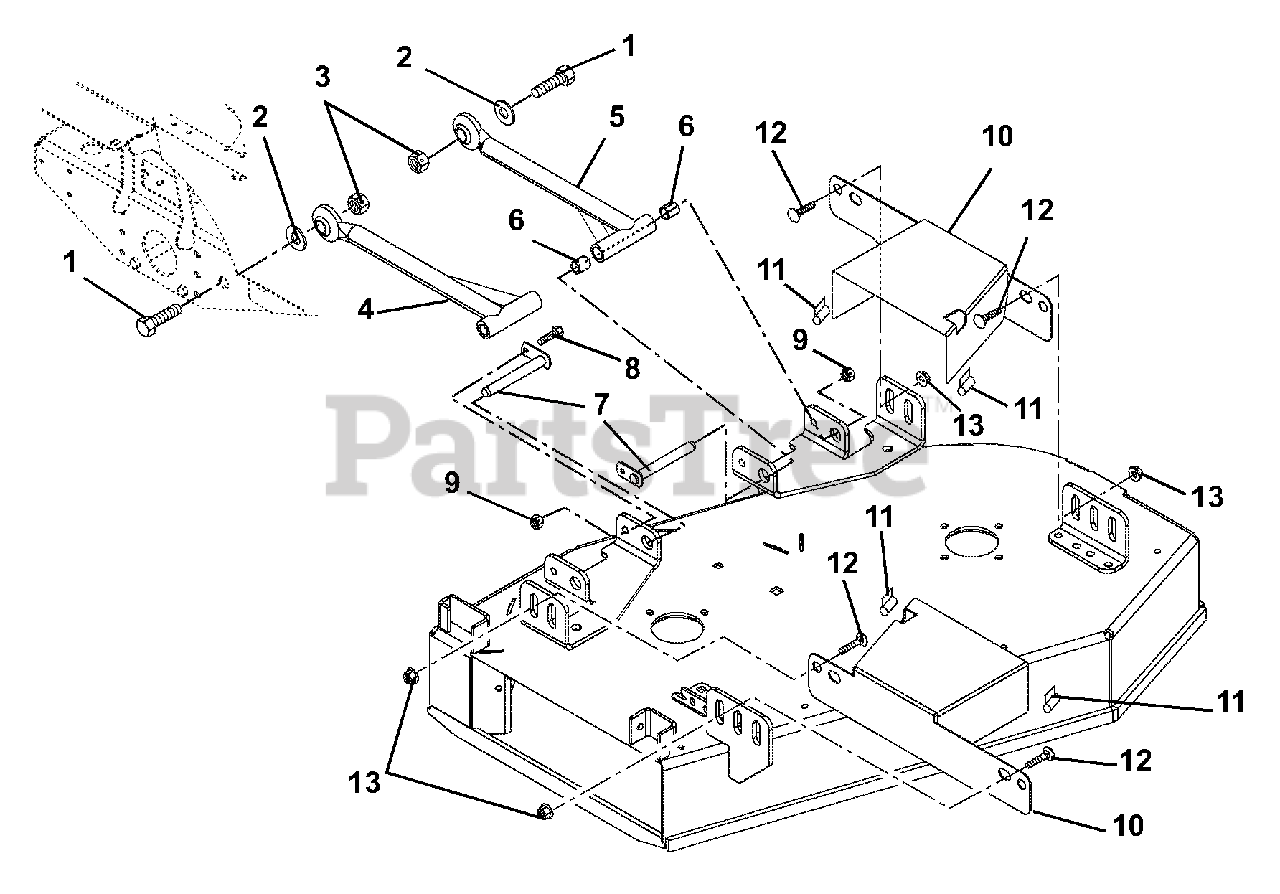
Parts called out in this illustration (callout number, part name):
1	BLT-HEX .875-9X3.00 GR5 YZ
2	BSHG-SLV .882X1.250X.531
3	NUT-LK-CTR .875-9 YWZC
4	ASSY, MOWER MOUNTING
5	MOWER MTG ARM - BLACK
6	BRG, .750 X .875 X 1.000
7	WELDMENT, MOWER MTG. PIN
8	BLT-HEX .38-16X.875 GR5 YWZC
9	@NUT-LK-TOP-FLG .38-16 YWZC
10	GUARD, 34" BELT
11	SEAL, TRIM-LOK BULK .06 BBL 1'
12	@BLT-RDHDSQNK .50-13X1.00 G5YZ
13	@NUT-LK-TOP-FLG .50-13 YWZC
